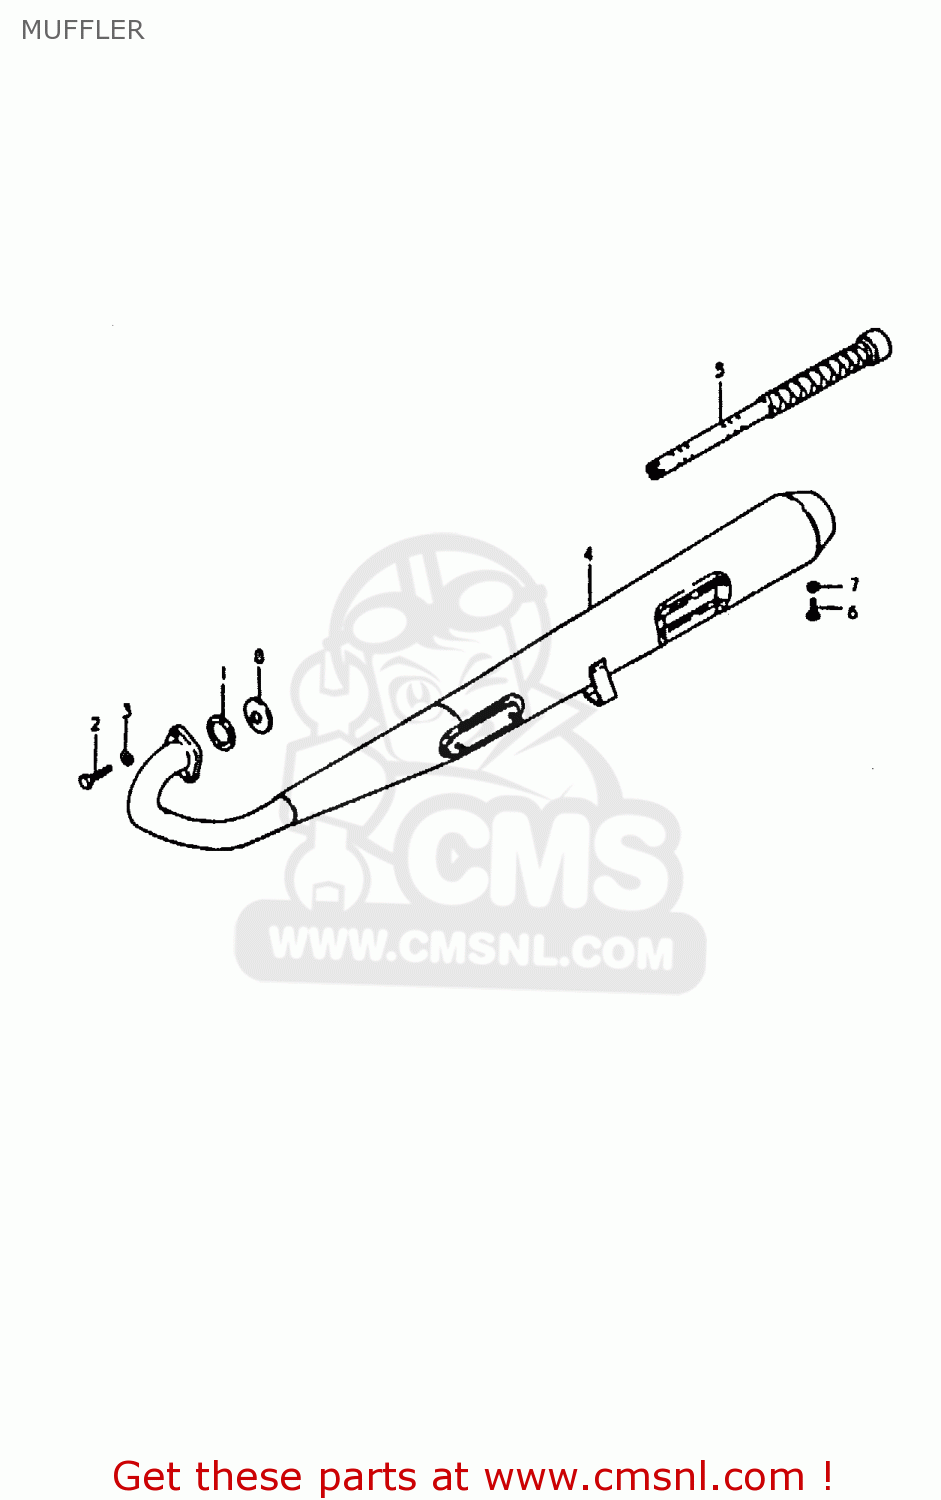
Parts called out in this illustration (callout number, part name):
1	GASKET, EXHAUST PIPE
2	BOLT
3	LOCK WASHER
4	MUFFLER ASSY
5	PIPE,BAFFLE
6	BOLT(5X8)
7	LOCK WASHER
